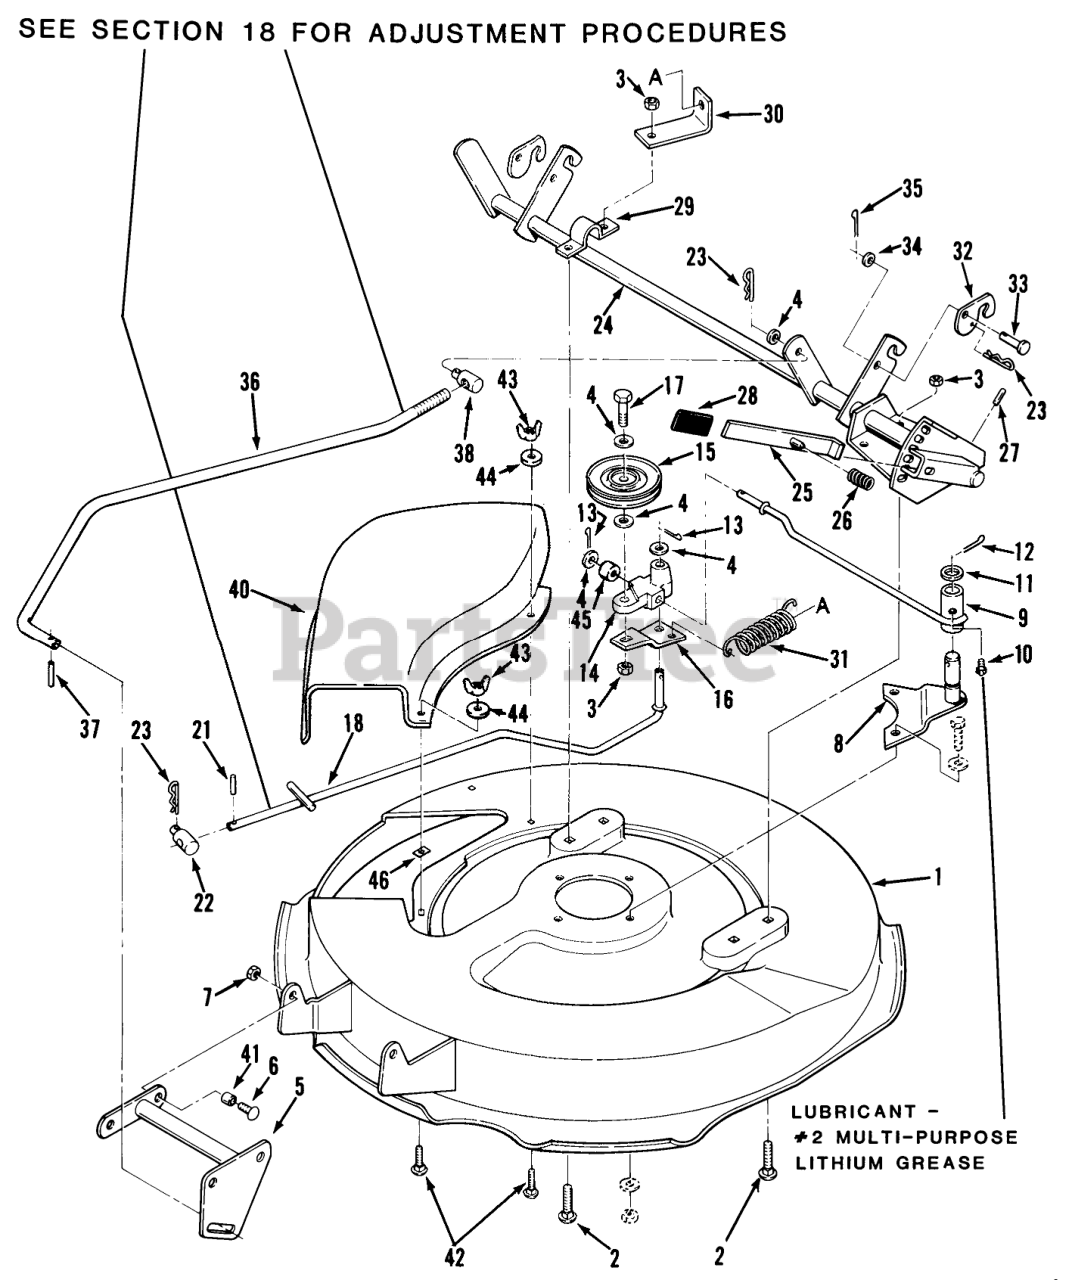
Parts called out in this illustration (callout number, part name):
5	ASM-FRONT LIFT *R
11	WASHER
14	BLOCK IDLER
15	PULLEY-IDLER V
22	TRUNNION-LIFT
23	Hairpin Cotter
25	LEVER ASSY
26	SPRING-COMPRESSION
27	PIN-SPIROL
29	CLAMP
31	SPRING-EXTENSION
36	ASS'Y-HEIGHT ADJ *R
37	SPIROL PIN
38	STUD-TRUNION
41	SPACER
44	WASHER
45	SPACER
46	SPEED NUT
